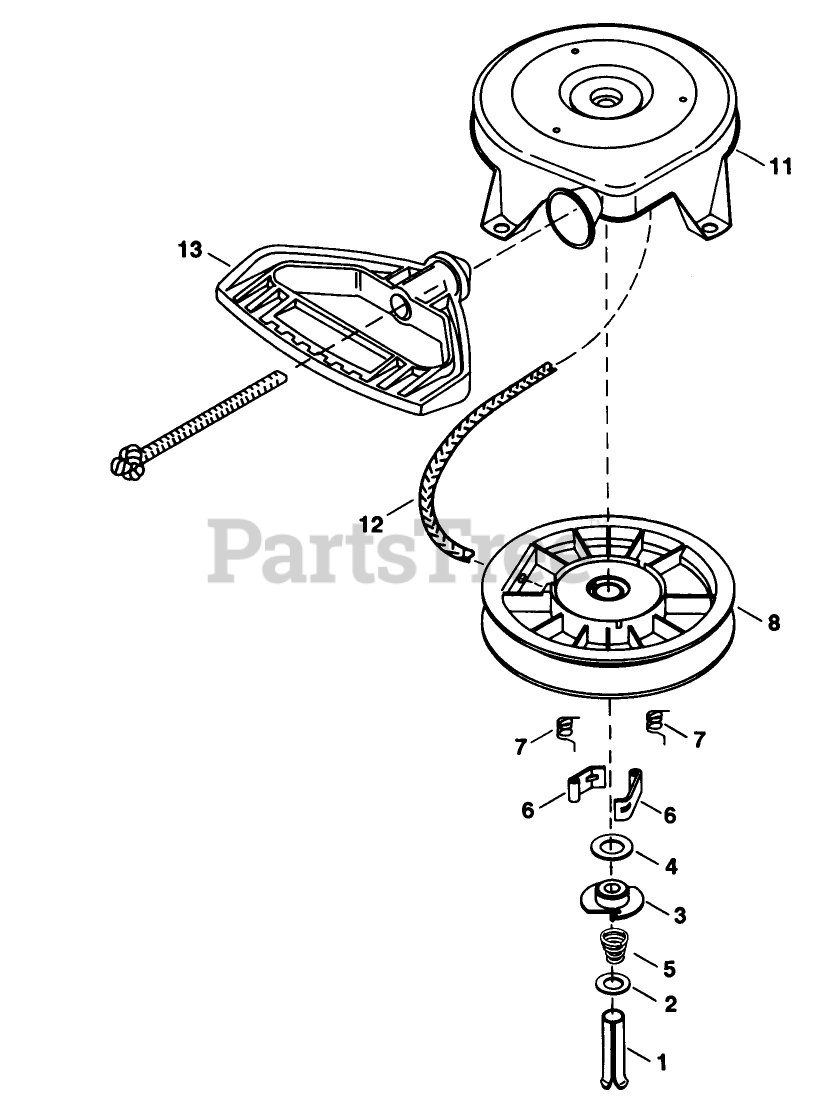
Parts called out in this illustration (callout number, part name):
1	Pin, Spring (Incl. Ref. #7)
2	Washer
3	Retainer
4	Washer
5	Spring-Brake
6	Dog-Starter
7	Spring-Dog
8	Pulley and Rewind Spring ASM
11	Housing Assy.-Starter
12	Rope-Starter
13	Handle-Starter, Mitten Grip
